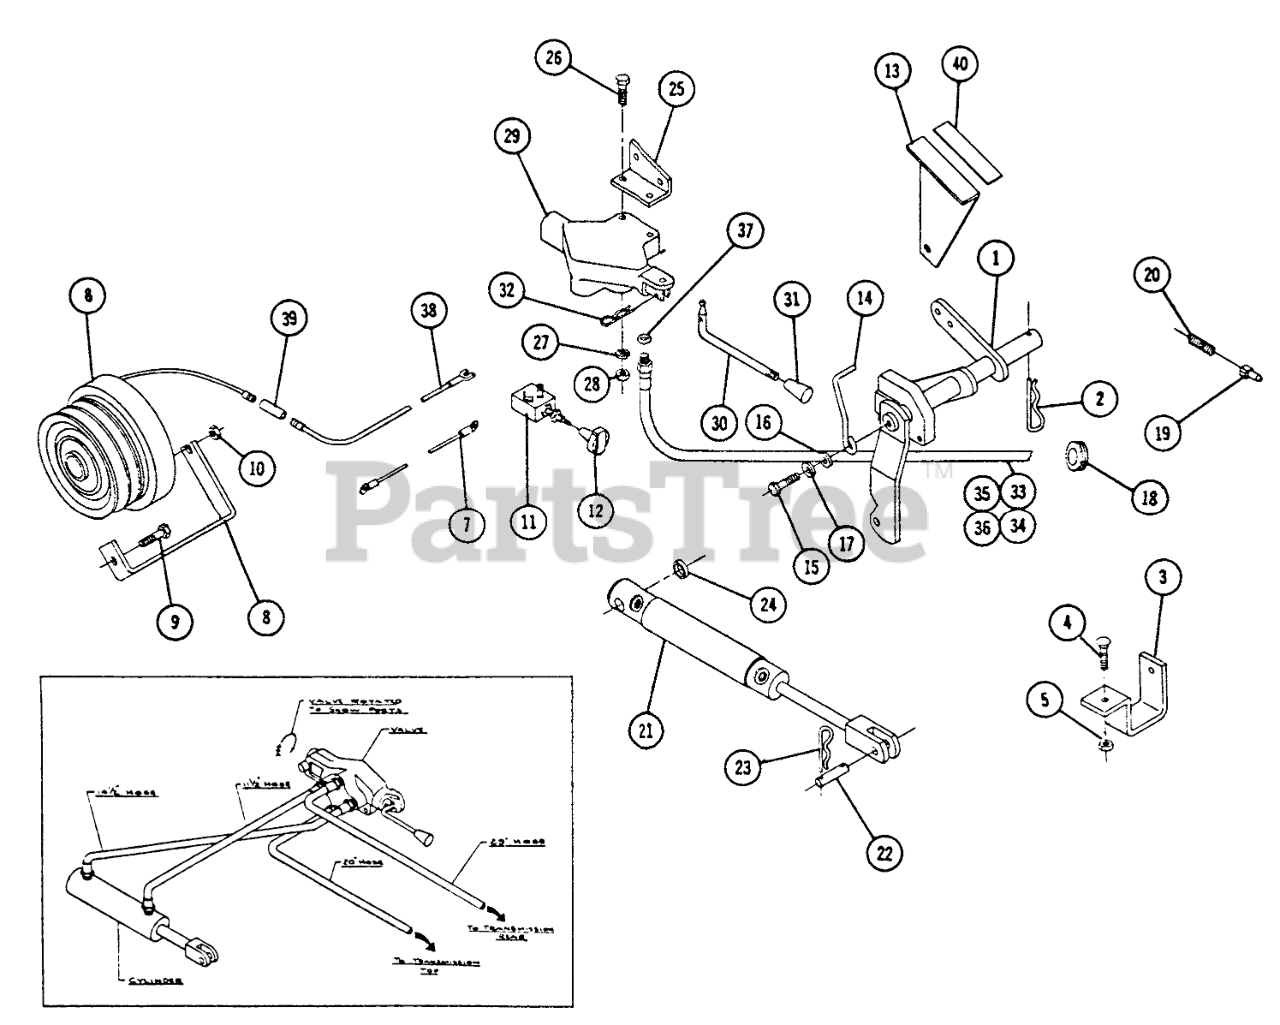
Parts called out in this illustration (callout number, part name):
2	Hairpen
3	Bracket
4	Bolt-Carriage 5/16-18
5	Nut 5/16-18
6	BULLT 298C
8	Bracket Clutch
9	Bolt Hex 7/16-4 x 3/4
10	Nut 1/4-28 Hex Head
14	Arm
15	Bolt 5/16-18 x
16	Washer
17	Lockwasher
23	Hairpin
26	Bolt Hex 1/4-20 x 1 1/4
27	Lockwasher
28	Nut-Nylok
32	Hairpin
37	O RING
40	Decal
